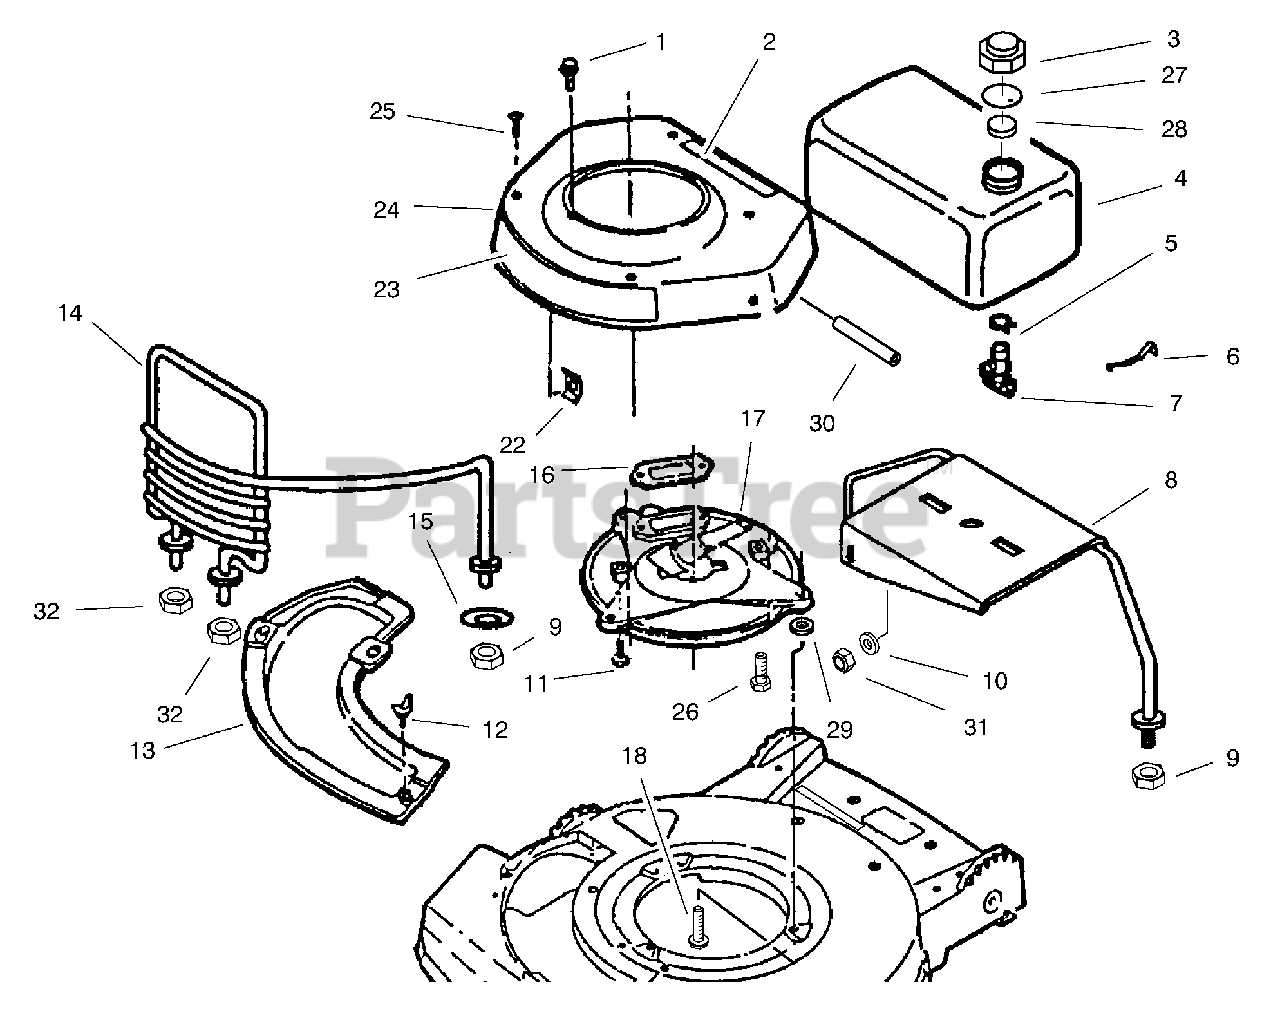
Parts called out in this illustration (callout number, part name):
1	Screw-Starter
2	Decal-Mixture, Fuel
3	Cap-Fuel
4	Tank-Fuel
5	Clamp-Valve to Tank
6	Spring-Mount., Fuel Tank
7	Valve & Screen-Shut-Off
8	Bracket-Tank, Fuel
10	Washer-Flat
11	Screw-Muffler Plate to Block
12	Screw-Wing
13	Plate-Cover
14	Guard-Engine
16	Gasket-Exhaust
17	Plate-Muffler
18	Screw-Muffler Plate to Housing
22	Retainer-Applique
23	Applique
25	Screw-Shroud to Base
29	Washer-Flat
30	Line-Gas
31	Nut-Lock
32	Nut-Lock
